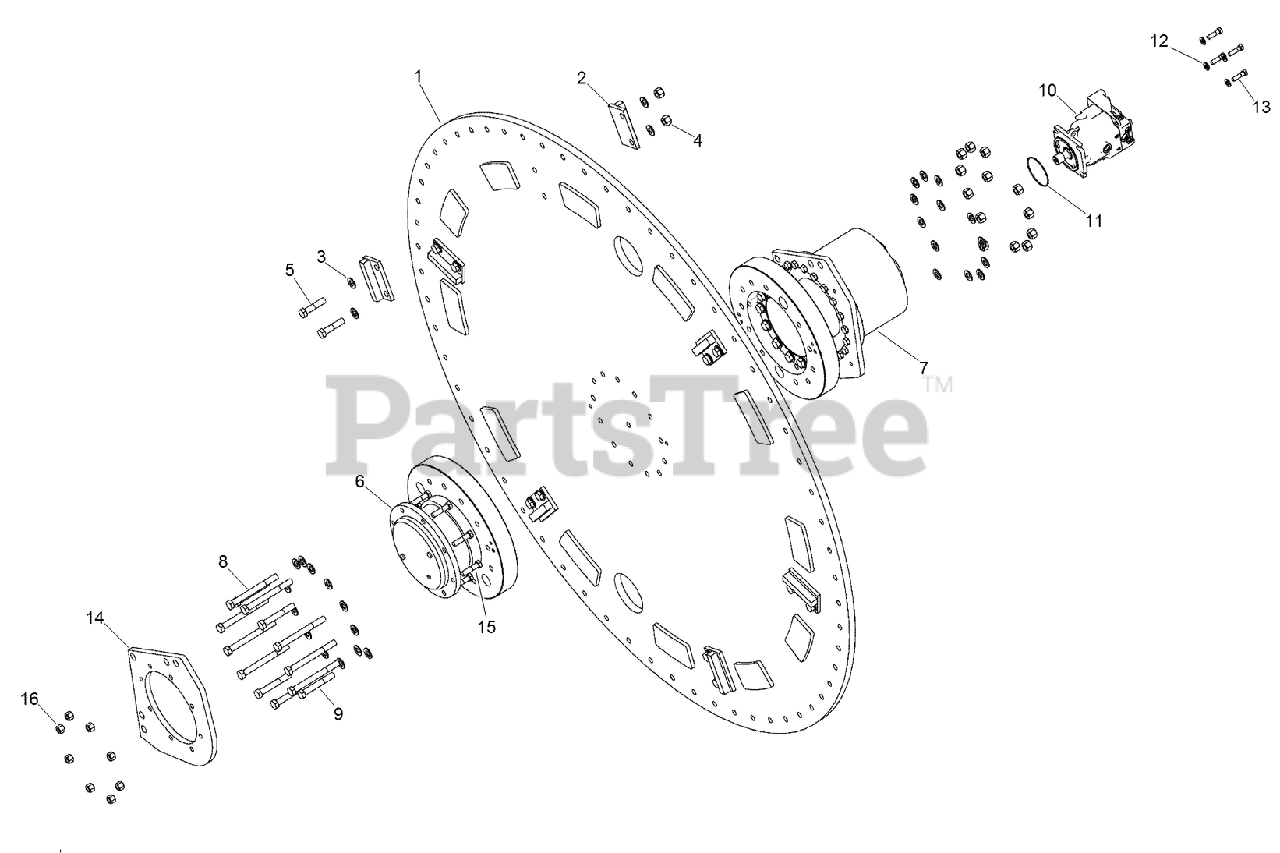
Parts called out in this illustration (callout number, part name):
1	WELDMENT - Wheel, 40 Cut
2	WELDMENT - Side Cutter
4	NUT-Prev Trq 3/4 GRC CAD Direct
5	BOLT - Hex Hd .75 x 3.25 GR8 ZND
6	ASSEMBLY - Model 9 Hub w/Adaptor Plate
7	ASSEMBLY - Model 10 Gearbox w/Adaptor Plate
8	BOLT - Hex Hd 0.75 x 7.50 GR8 ZND
9	BOLT - 3/4 x 5
10	PUMP - Sauer-Danfoss, 90 Series, 55cc
11	O-RING-Motor Seal
12	WASHER-FLAT
13	BOLT-Hex Hd 1/2 x 1-3/4 GR5 ZND
14	PLATE - Hub Mount
15	BOLT - 5/8 x 2-1/2
16	NUT-LOCK, HEX
